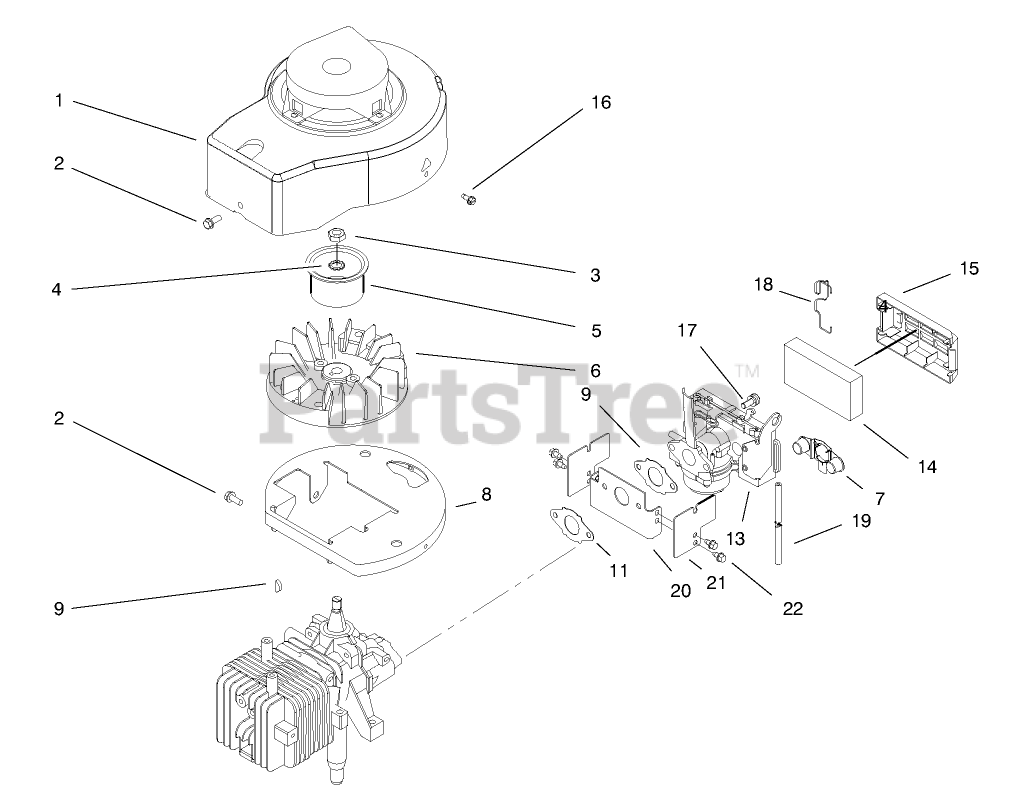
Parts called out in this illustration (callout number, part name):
5	HUB-STARTER V
7	SHIELD-FUEL V
11	GASKET-CARB VF
13	CARBURETOR ASM
15	COVER-AIR FIL. V
16	SCREW VF
17	SCREW
18	RETAINER-COVER, FILTER
19	HOSE-PRIMER
20	SHIELD-CARB V INTL
21	SHIELD- GOV. V INTL
22	SCREW
